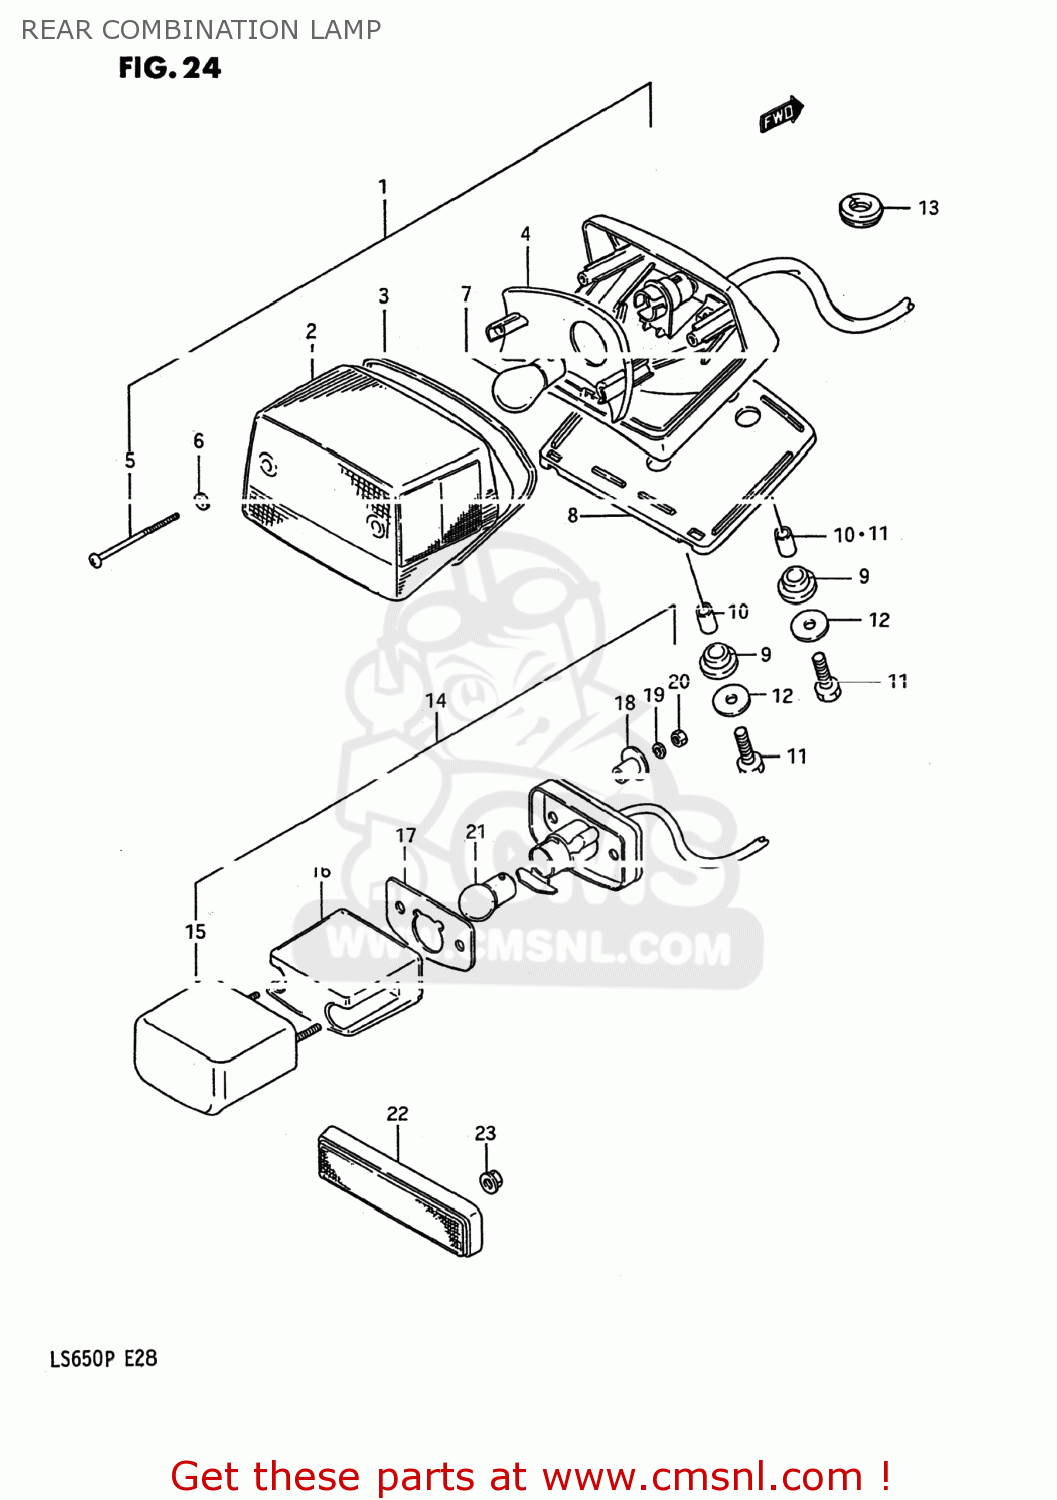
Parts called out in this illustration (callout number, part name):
1	LAMP ASSY,RR COMBINATION
2	LENS
3	GASKET (NAS)
4	REFLECTOR
5	SCREW
6	GASKET (NAS)
7	BULB(12V23/8W,TOKAI DENSO)
8	CUSHION
9	CUSHION
10	SPACER
11	SPACER
12	BOLT 6X25
13	GROMMET
14	LAMP ASSEMBLY,LICENSE
15	COVER,LICENSE LAMP
16	LENS
17	GASKET,LICENSE LAMP (NAS)
18	SPACER
19	WASHER,LOCK 4M
20	NUT
21	BULB(12V8W)
22	REFLEX REFLECTOR ASSY,RR
23	NUT
